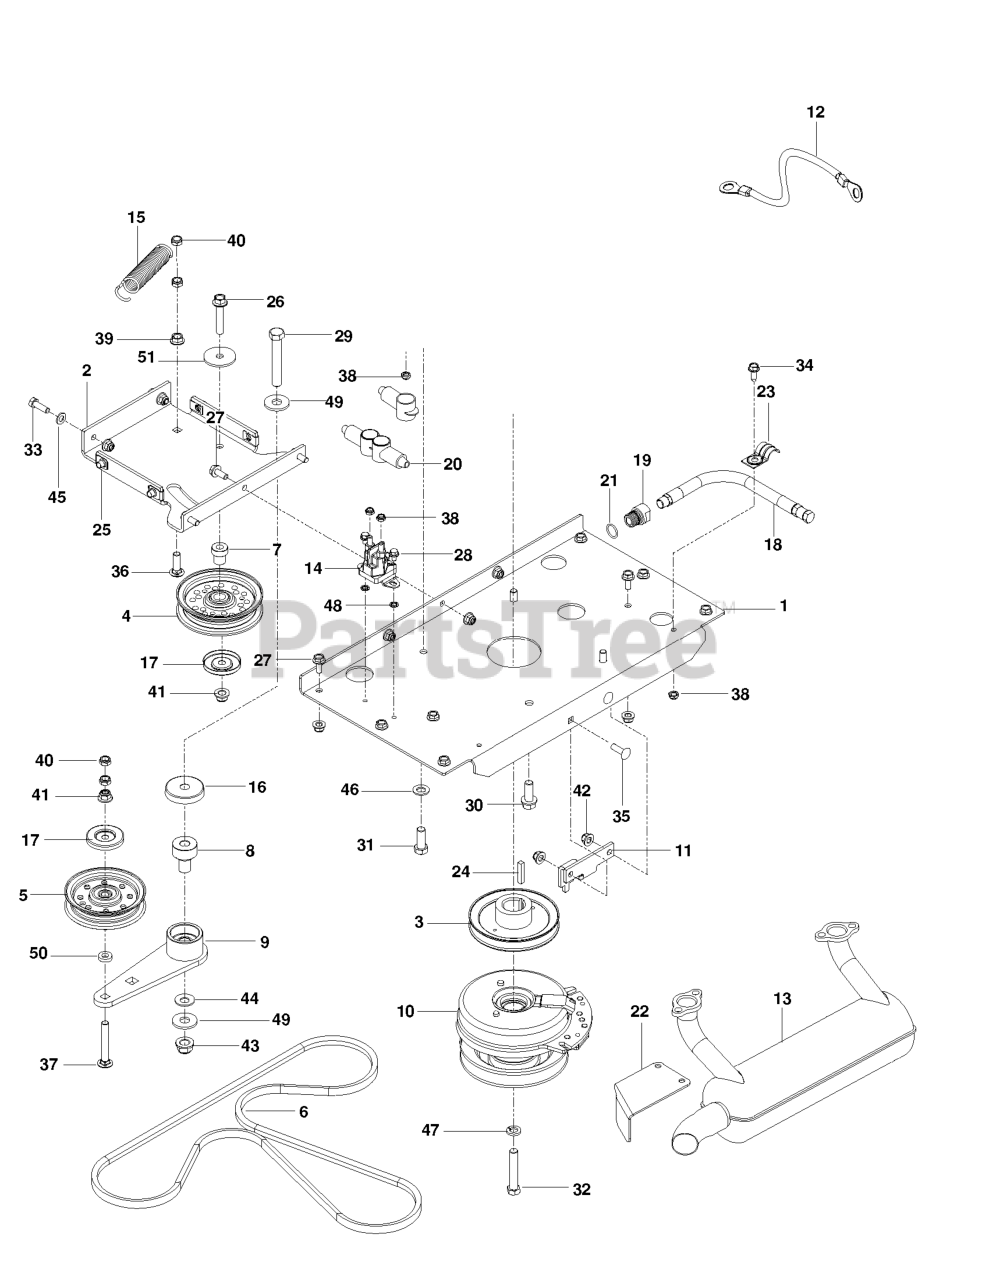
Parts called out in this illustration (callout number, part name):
1	PLATE, ENGINE, BLK
2	PLATE, IDLER, BLK
3	PULLEY, V, 1.125 BORE
4	IDLER PULLEY
5	FLAT IDLER PULLEY
6	BELT, HYDRO, 3400
7	PIVOT, IDLER
8	PIVOT, BEARING
9	ARM, IDLER, STEEL, W/BGS
10	CLUTCH 200 FT LB
11	STOP, CLUTCH, BLACK
12	CABLE POSITIVE
13	MUFFLER.26HP.KAW.FX651V-730V
15	SPRING, PUMP
16	SHIELD, DUST
17	DUST SHIELD
18	HOSE.ASSEMBLY.OIL.DRAIN
19	ADAPTER, OIL DRAIN
22	SHIELD MUFFLER
24	KEY, 1/4 SQ X 1 1/4
25	U-CLIP 5/16-18 NUT RETAINER
26	HHFS 3/8-16 X 2.0 GD 5
27	HHFS 5/16-18 X 3/4
28	HWST 1/4C X 3/8
29	HCS 1/2C X 3 1/4
30	4CS 3/8C X 1 SERRATED HEAD
31	HCS 3/8-16X1.GRD.5.ZD
32	BOLT 7/16F X 2 1/2
33	HCS 5/16C X 1
34	HCS 1/4-20.
35	RHSSNB 5/16C X 1.0
36	RHSNB 3/8-16 X 1-1/4
37	RHSNB 3/8-16 X 2.75
38	JAM NUT 1/4C (2 2 PW01)
39	NUT 3/8C WHIZ
40	NUT HEX 3/8-16 NYLON, THIN
41	NUT 3/8-16 HEX FLG NYLOC ZD
42	5/16-18 NYLOC FLANGE NUT
43	NUT, 1/2-13 HEX FLG NYLOC ZD
44	CONTACT BELLSPR 1/2
45	FLAT WASHER 5/16 SAE
46	WASHER, 3/8 DISC SPRING SPEC
47	WASHER 7/16 LOCK
48	WASHER 1/4 INT TOOTH
49	WASH USS FLAT 1/2
50	WASHER 3/8 X 3/4 X .187 TK
51	WASHER, 3/8 SPEC
